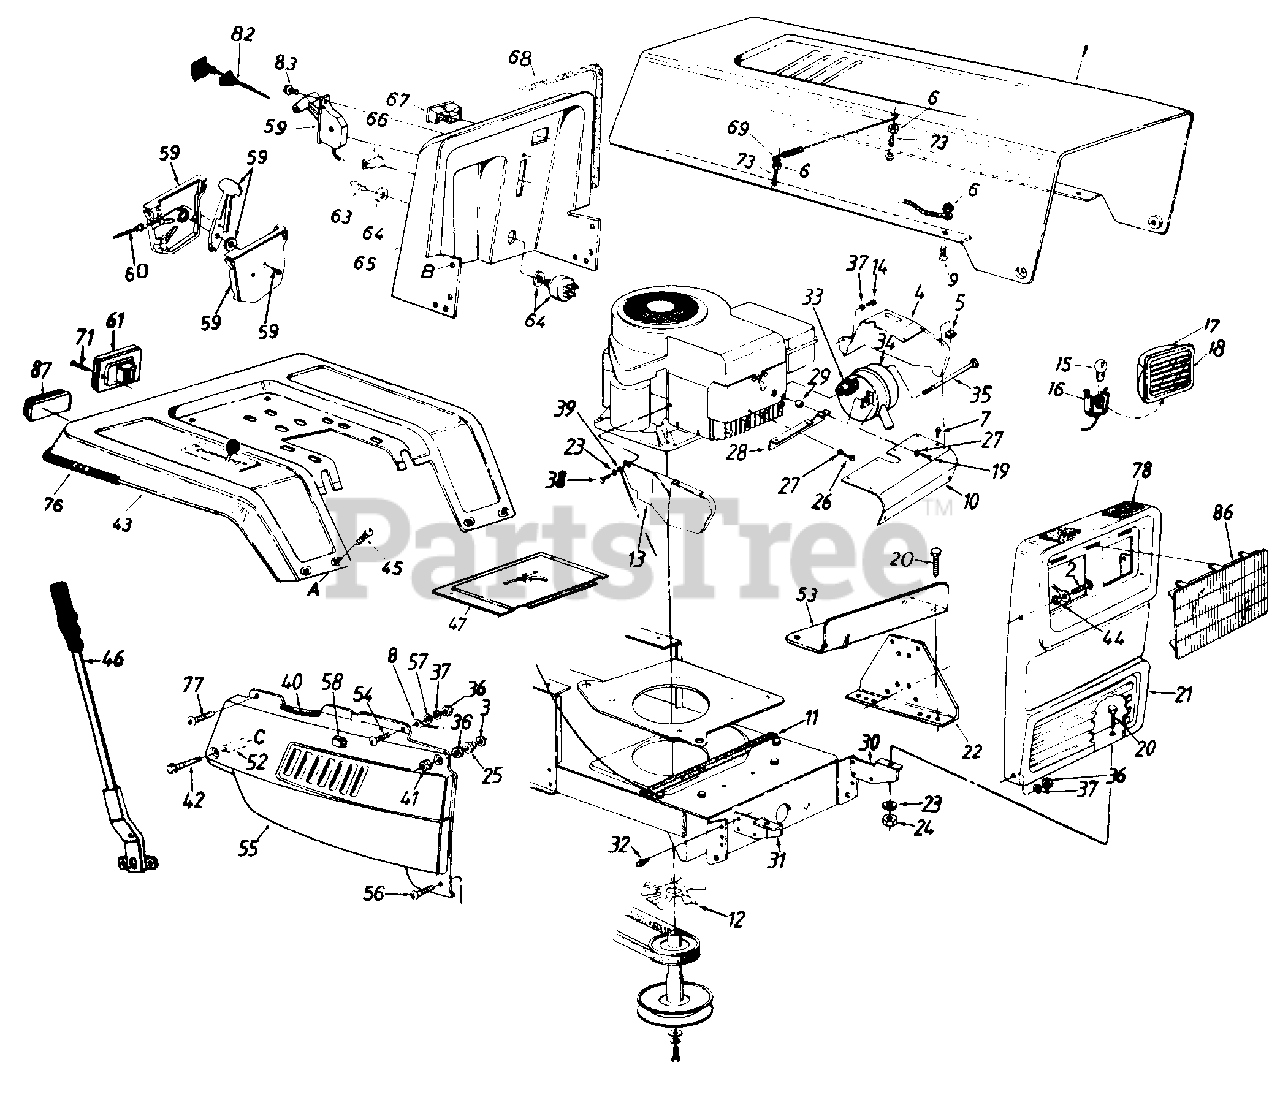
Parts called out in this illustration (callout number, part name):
1	Hood
2	Hex Bolt 1/4-20 x .88" Lg.
3	Washer .39" I.D. x .62"
4	Muffler Heat Shield-L.H.
5	Speed Nut #10-24 Thd.
6	Hex Sems Nut #10-24 Thd.
7	Hex AB-Tap Scr. #10 x .5" Lg.
8	Hood Stop
9	Truss Hd. Scr. #10-24 x 1/2"
10	Muffler Heat Shield-Front
11	Foam Strip
13	Muffler Heat Shield-R.H.
14	Hex Tap Scr. 1/4-20 x .5" Lg.
15	Lamp
16	Twist Lock-Lamp Socket
17	Headlight Housing
18	Lens
19	Hex Bolt 1/4-20 x .85" Lg.
20	Hex Bolt 5/16-18 x .75" Lg.
23	L-Wash. 5/16" I.D.
24	Hex Nut 5/16-18 Thd.
25	Shld. Spacer
26	Hex Bolt 1/4-20 x 3/8" Lg.
27	Spr. Wash. 1/4" I.D.
28	Heat Shield Bracket
29	Spacer
30	Grille Mount Brkt.-L.H.
33	Exhaust Gasket
35	Shoulder Bolt
36	Hex Nut 1/4-20 Thd.
37	L-Wash. 1/4" I.D.
38	Truss Mach. Scr. 5/16-18 x .75" Lg.
39	Ground Wire
40	Trim Strip-6"
41	Acron Nut 1/4-20 Thd.
42	Hex TT-Tap Scr. 1/4-20 x 1.75" Lg.
45	Carriage Bolt 1/4-20 x .50"
46	Lift Handle
47	Transmission Panel
52	Spacer 1.30" Lg.
53	Fuel Tank Support
54	Truss Hd. Scr. 1/4-20 x .75"
55	Side Cover-R.H.
56	Truss Mach. Scr. 1/4-20 x .50" Lg.
57	Fl-Wash. .281" I.D. x .73" O.D.
58	Mounting Clamp
59	Throttle Control Box Ass'y.
60	Throttle Control Wire
61	Taillight
63	Ignition Key
64	Ignition Switch
67	Ammeter
68	Trim Strip-27"
69	Hood Spring
71	Truss Hd. AB-Tap Scr. #6 x .62" Lg.
73	Hex Scr. #10-24 x 1.0" Lg.
76	Trim Strip-81"
77	Hex Wash. Hd. Tap Scr. 1/4 x .75" Lg.
78	Foam Strip 3/8 x 1-1/8" x 11/2 Lg.
82	Choke Control 29" Lg.
83	Truss Mach. AB-Tap Scr. #10 x .5" Lg.
86	Headlight Bezel
87	Reflector
